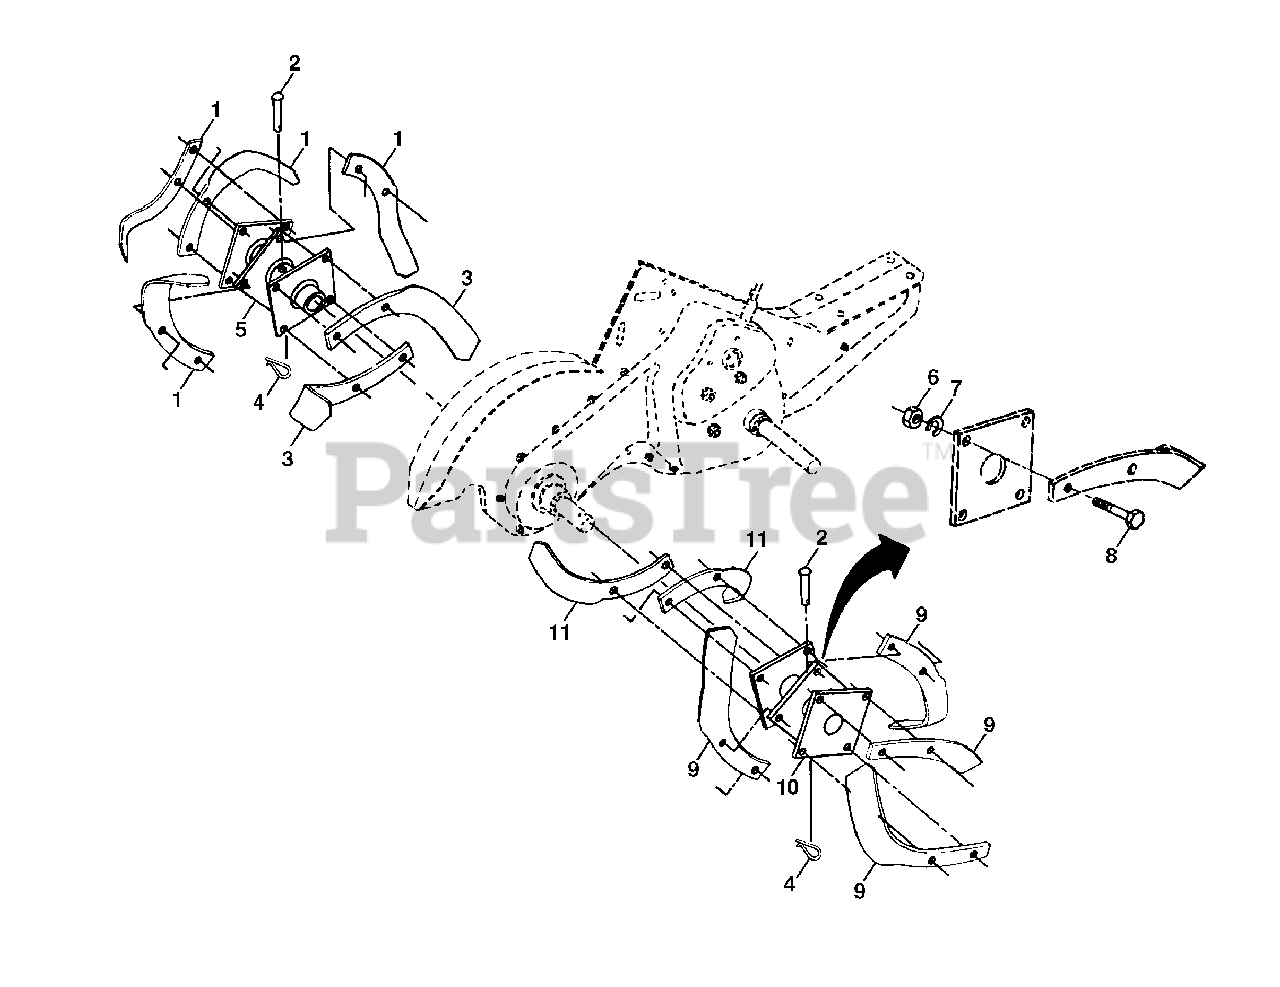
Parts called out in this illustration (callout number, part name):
1	Tine, Outer, L.H.
2	Clevis Pin
3	Tine, Inner, L.H.
4	Retainer, Spring
5	Assembly, Hub and Plate, L.H.
6	Nut, Hex 3/8-24
7	Washer, Lock 3/8
8	Bolt, Hex 3/8-24 x 1
9	Tine, Outer, R.H.
10	Assembly, Hub and Plate, R.H.
11	Tine, Inner, R.H.
